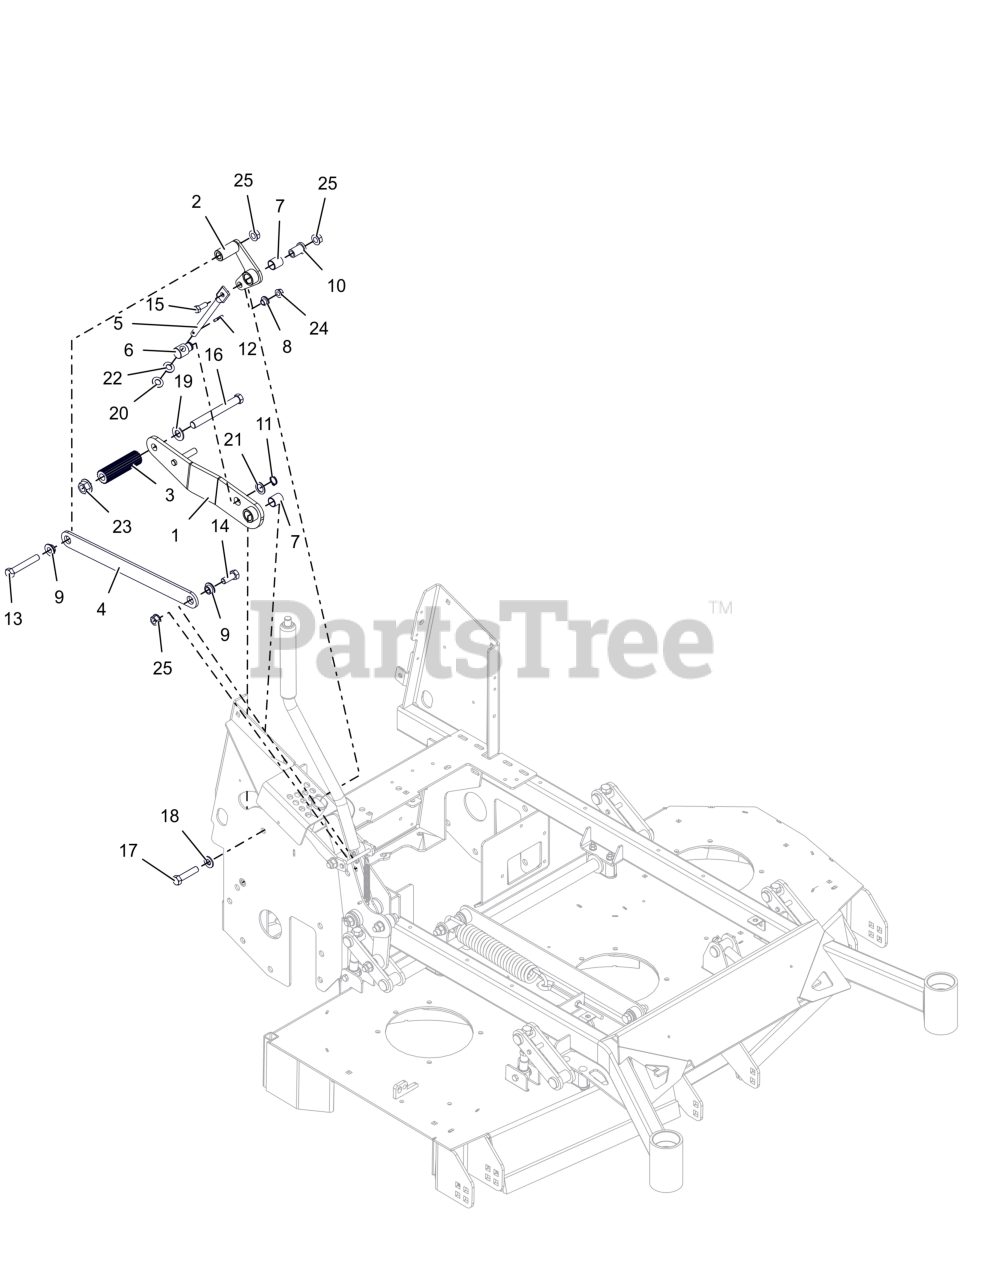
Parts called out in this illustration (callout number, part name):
1	BRKT, DECK LIFT FOOT PEDDLE
2	WLDMT, PIVOT BRKT
3	ROD, FOOT PEDAL (BLACK)
4	LINK,DECK LIFT FOOT ASSIST
5	LINK, HOC FOOT
6	TRUNNION,DECK LIFT FOOT ASSIST
7	BRG, .750 X .875 X 1.000
8	BSHG-FLG .385X.500X.875X.406
9	BSHG, FLG .515X.750X.360X1.12
10	BSHG-FLG .515X.746X1.290X1.000
11	RG-RTNG-EXT .689X.078
12	PIN-GRV .188X1.00 TP E
13	BLT,HEX .50-13X3.25 G5 ZCC
14	BLT,HEX .50-13X1.25 G5 ZCC
15	BLT,HEX .38-16X1.00 G5 ZCC
16	BLT, HEX .62-11X5.50 G5 FBP
17	BLT, HEX .50-13X2.25 G5 ZCC
18	WSHR,FLT .531X1.062X.095 ZCC
19	WSHRFLT 5/8SAE CARBHARD FBP
20	WSHR, FLT .531X1.00X.063 ZCC
21	WSHR, FLT .754X1.125X.062 ZCC
22	WSHR, RUBBER .332X1.000X.094
23	NUT,FLG-TOP LK .625-11 FBP
24	NUT-LK-CTR-FLG .375-16 GF ZCC
25	NUT-LK-CTR-FLG .500-13 GG ZCC
